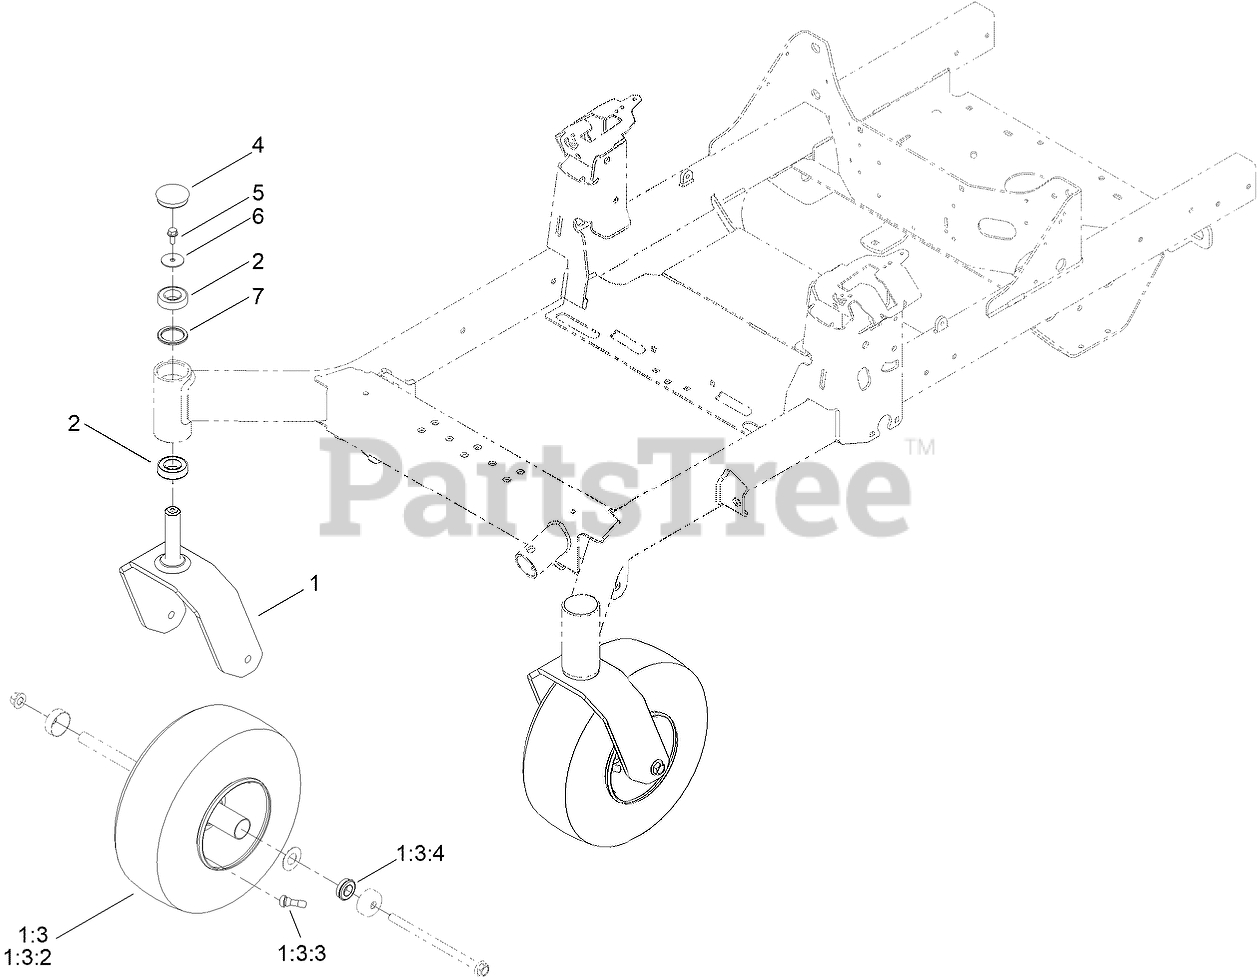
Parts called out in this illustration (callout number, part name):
1	ASM, FRONT CASTER W/FORK
1:3	TIRE AND WHEEL ASM
1:3:4	BEARING
2	BEARING-BALL
4	CAP,GREASE
5	SCREW-HHF
6	WASHER-FLAT
7	SPACER-BEARING
